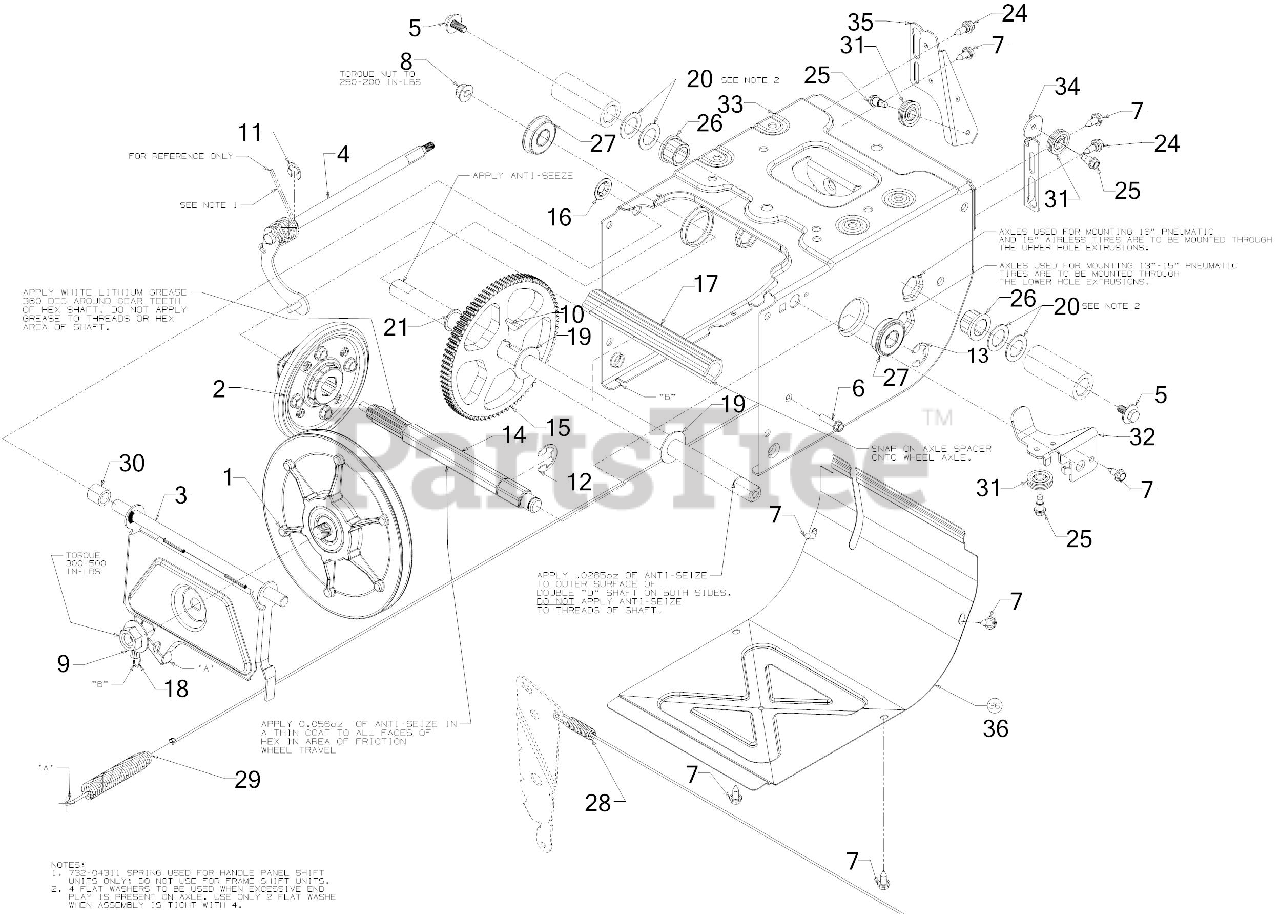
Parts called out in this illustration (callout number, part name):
1	FRICTION WHEEL DISC ASSEMBLY
2	FRICTION WHEEL ASSEMBLY
3	FRICTION WHEEL BRACKET
4	SHIFT ROD ASSEMBLY
5	SCREW 5/16-24 x .750 GR5
6	SCREW 1/4-20 x 1.00
7	SCREW 1/4-20X.625
9	FLANGE NUT 5/8-18
10	KEY 3/16 x 3/4
11	E-RING FOR .500
12	RETAINING RING
13	E-RING
14	HEX SHAFT .812
15	GEAR:80 TOOTH
16	PUSH CAP
17	SPACER-AXLE 7.40"
18	EXTENSION SPRING
19	FLAT WASHER .760ID X1.49OD x .06
20	FLAT WASHER .793ID x 1.24OD x .060
21	FLAT WASHER .750X1.000X.060:HD
24	SHOULDER SCREW
25	SHOULDER SCREW
26	FLANGE BEARING
27	BALL BEARING
28	AUGER DRIVE CABLE 47.48"
29	WHEEL DRIVE CABLE 44.955"
30	SPACER-.513 ID x .703 OD x .69
31	CABLE GUIDE ROLLER
32	AUGER CABLE BRACKET
34	AUGER CABLE GUIDE BRACKET
35	GUIDE BRACKET
